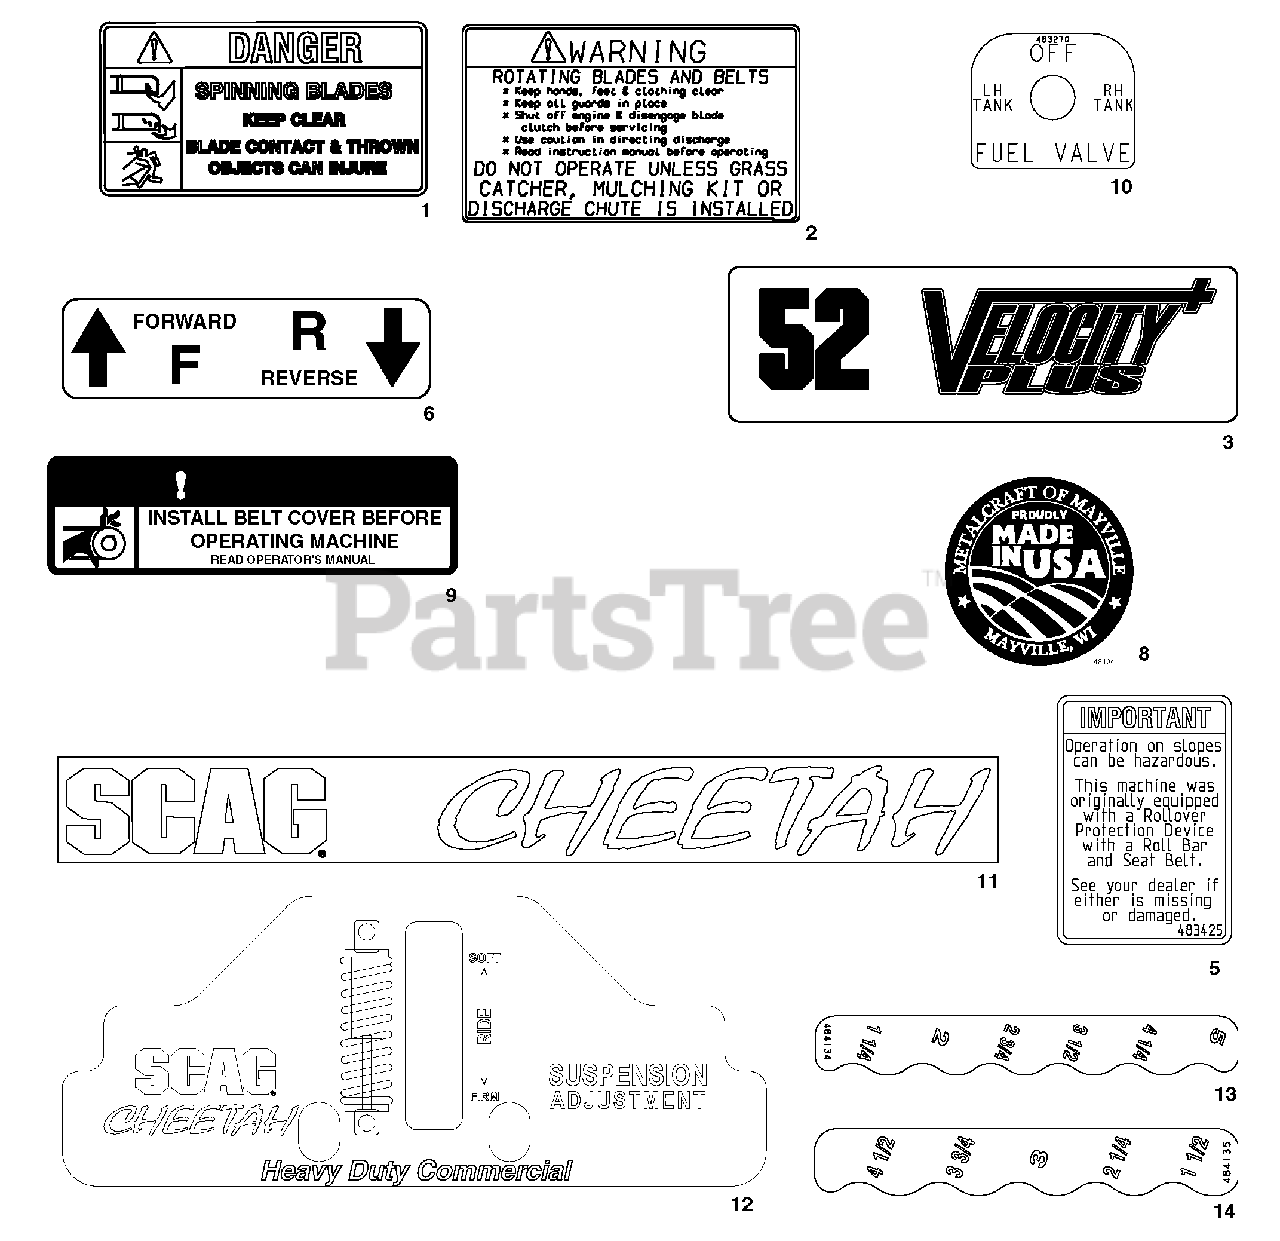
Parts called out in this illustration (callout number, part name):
1	Decal, Spinning Blades
2	Decal, Knives
3	Decal, 48" Velocity Plus
3	Decal, 52" Velocity Plus
5	Decal, ROPS
6	Decal, Traction Control
8	Decal, Made in USA
9	Decal, Belt Cover
10	Decal, Fuel Shut Off
11	Decal, Scag Cheetah
12	Decal, Suspension Adjustment
13	Decal, Deck Height - LH
14	Decal, Deck Height - RH
19	Decal, ROPS
